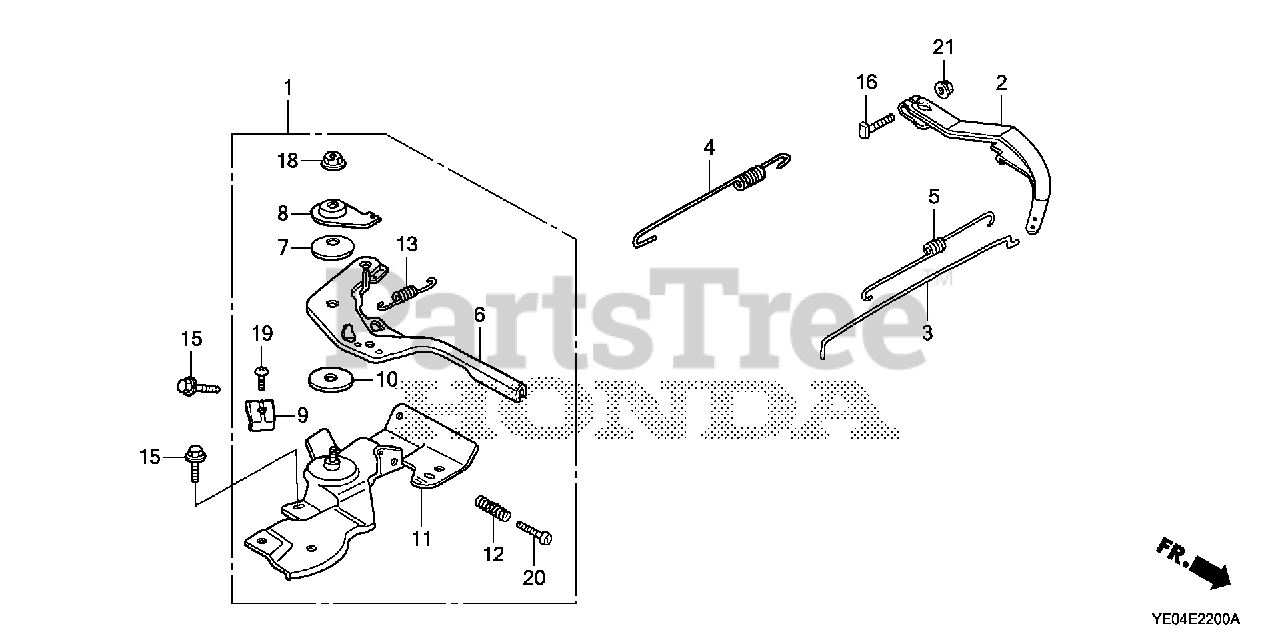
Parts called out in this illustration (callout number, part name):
1	CONTROL ASSY. (REMOTE)
2	ARM, GOVERNOR
3	ROD, GOVERNOR
4	SPRING, GOVERNOR
5	SPRING, THROTTLE RETURN
6	LEVER, CONTROL
7	SPRING, LEVER
8	WASHER, CONTROL LEVER
9	HOLDER, CABLE
10	SPACER, CONTROL LEVER
11	BASE, CONTROL (REMOTE)
12	SPRING, CONTROL ADJUSTING
13	SPRING, CABLE RETURN
15	BOLT, FLANGE (6X12) (CT200)
16	BOLT, GOVERNOR ARM
18	NUT, SELF-LOCK (6MM)
19	SCREW, PAN (5X16)
20	SCREW, PAN (5X25)
21	NUT, FLANGE (6MM)
